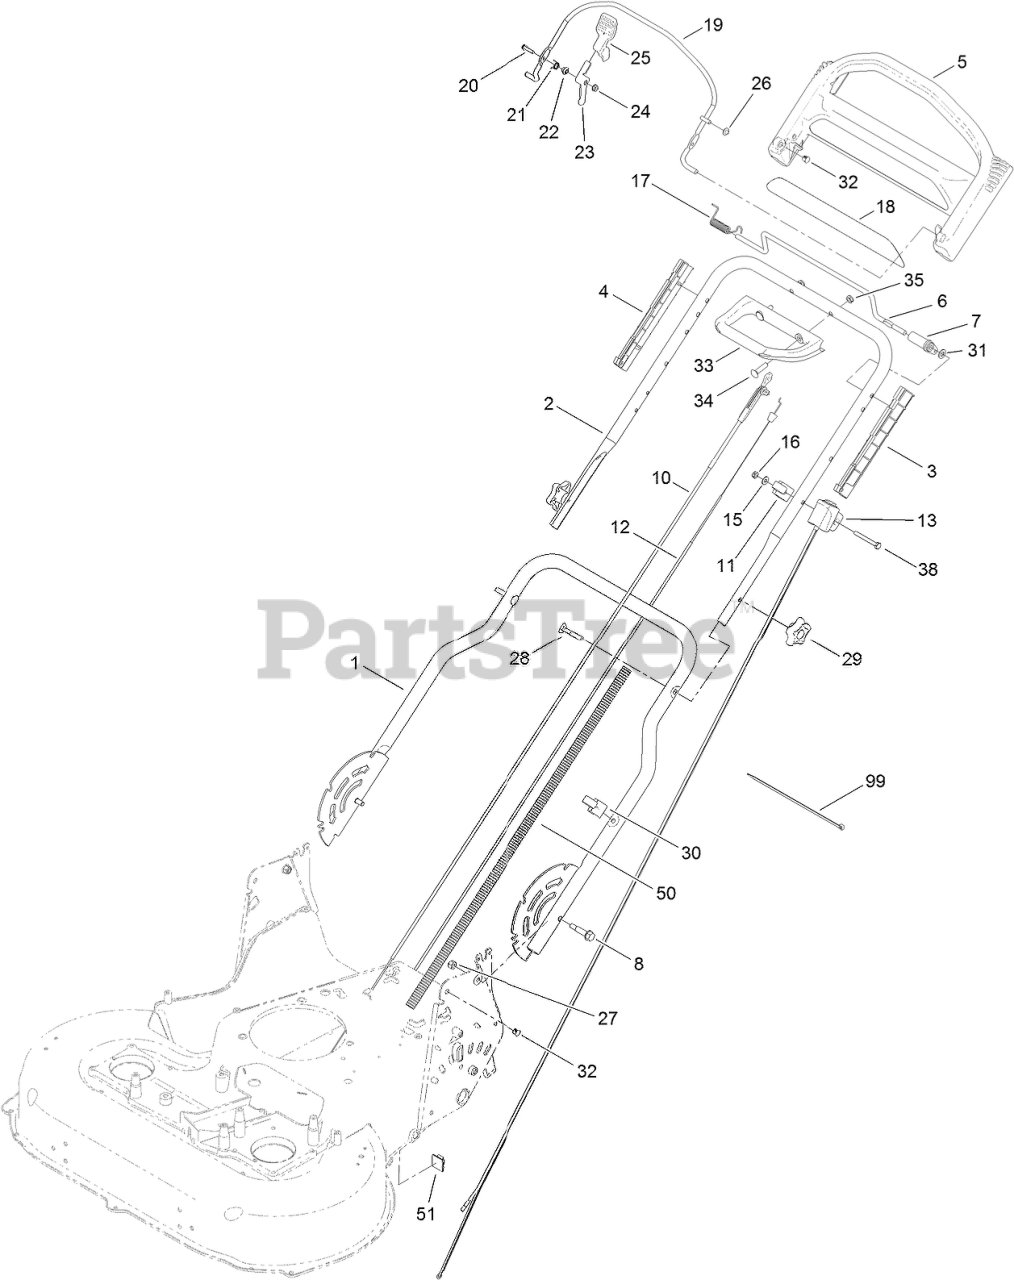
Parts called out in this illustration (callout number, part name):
1	HANDLE-LOWER
2	HANDLE-UPPER
3	GUIDE-LH
4	GUIDE-RH
5	HANDLE-CONTROL
6	BAR-CONTROL, TRACTION
7	LEVER-TRACTION
8	BOLT-SHOULDER, HHF
10	CABLE-BRAKE, BBC
11	ANCHOR-CABLE
12	CABLE-TRACTION
13	SWITCH HOUSING ASM
15	WASHER-FLAT
16	NUT-LOCK, NI
17	Spring-Torsion
19	BAIL-BRAKE
20	SCREW-HWH
21	SPRING-TORSION
22	SPACER
23	LEVER
24	NUT-LOCK, FLANGE
26	NUT-SPEED
27	NUT-LOCK, NI
28	SCREW-HANDLE
29	KNOB-HANDLE
30	GUIDE-CABLE
31	WASHER-PLAIN
32	Plug-Dome
33	HANDLE-ASSIST, TRACTION
34	BOLT-CARRIAGE
35	NUT-LOCK, NI
38	SCREW-HH
50	CONDUIT-CONVOLUTED
51	GUIDE-CABLE
99	TIE-CABLE
